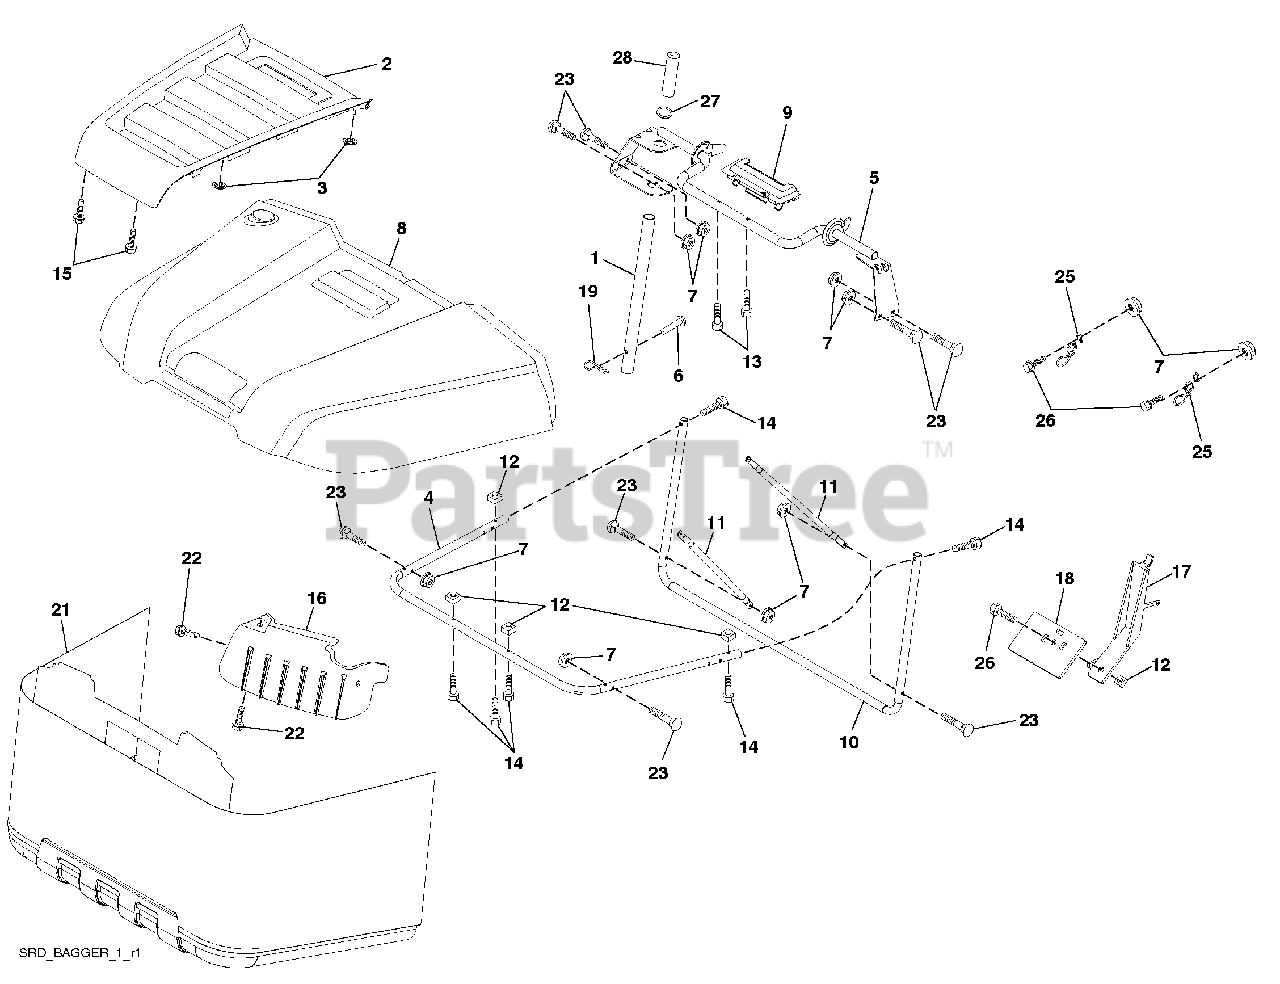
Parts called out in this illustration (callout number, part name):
1	Tube Handle Bagger SRD
2	Applique Top Bagger
3	Nut Push
4	Frame Asm Bagger Top
5	Frame Asm Top Bagger SRD
6	Drilled Rivit
7	Nut Hex Flange 1/4-20 unc
8	Cover Bagger SRD
9	Insert Handle Bagger
10	Frame Front
11	Tubing Brace Bagger
12	Nut Square 1/4
13	Screw 1/4 x 1.150 HXWSH
14	Bolt Shoulder HX WSH 1/4 x 1.150
15	Screw #8 Flat Head Drill Tip
16	Deflector Bagger
17	Lever Bagger Full
18	Paddle Bagger Full
19	Retainer Spring
21	Bag Asm SRD
22	Screw Hex WSH Hi-Lo 1/4 - 1/2 unc
23	Bolt Carr 1/4-20 unc x 1-1/4
25	Spring Latch Bagger
26	Screw Hex Thdrol 1/4-20 x 3/4
27	Grommet, Rubber SRD
28	Grip Handle Black
